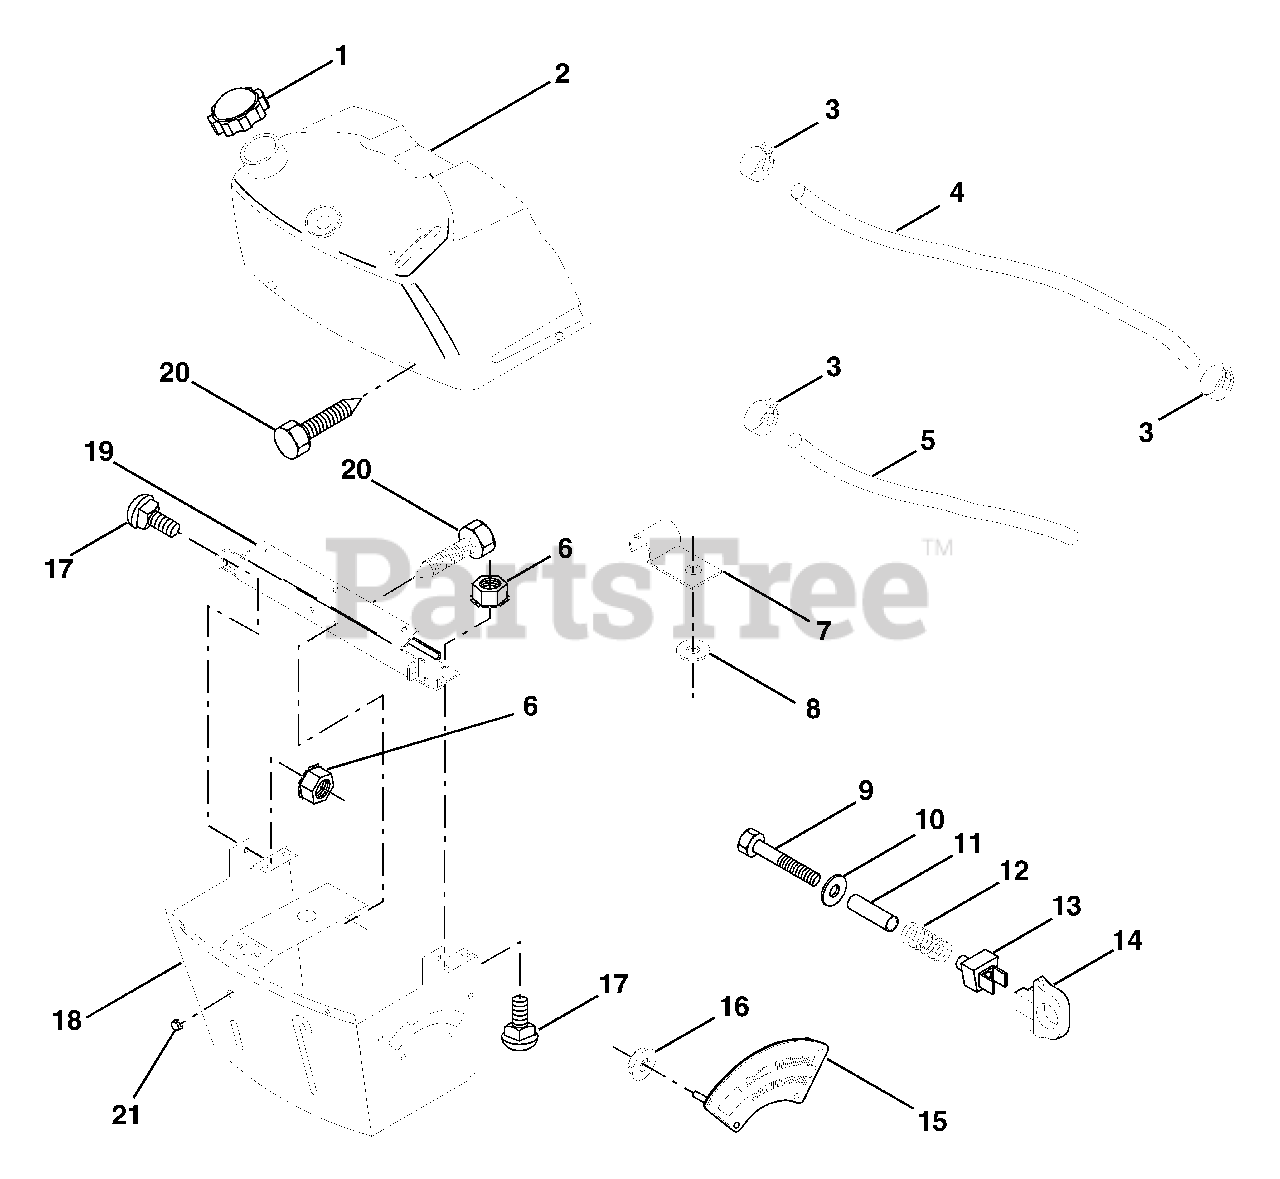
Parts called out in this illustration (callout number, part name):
2	Assembly, Dash & Fuel Tank
3	Clamp, Hose
4	Line, Fuel
5	Line, Fuel
6	Nut, Hex, Keps 1/4-20
7	Clip, Fuel Line
8	Washer 9/32 x 3/4 x 16 Ga.
9	Bolt, Hex, Fin 1/4-20 x 1-3/4
10	Washer 11/32 x 11/16 x 16 Ga.
11	Spacer, Split
13	Clip, Height Adjustment
14	Knob, Height Stop
15	Adjustment, Quadrant Height
16	Nut, Self-Threading 3/16-18
17	Bolt, Carriage 1/4-20 x 1/2 Gr. 5
18	Support, Assembly Dash
19	Brace, Cross
20	Screw, Self-Tapping 1/4-20 x 1/2
21	Plug, Dome Black
